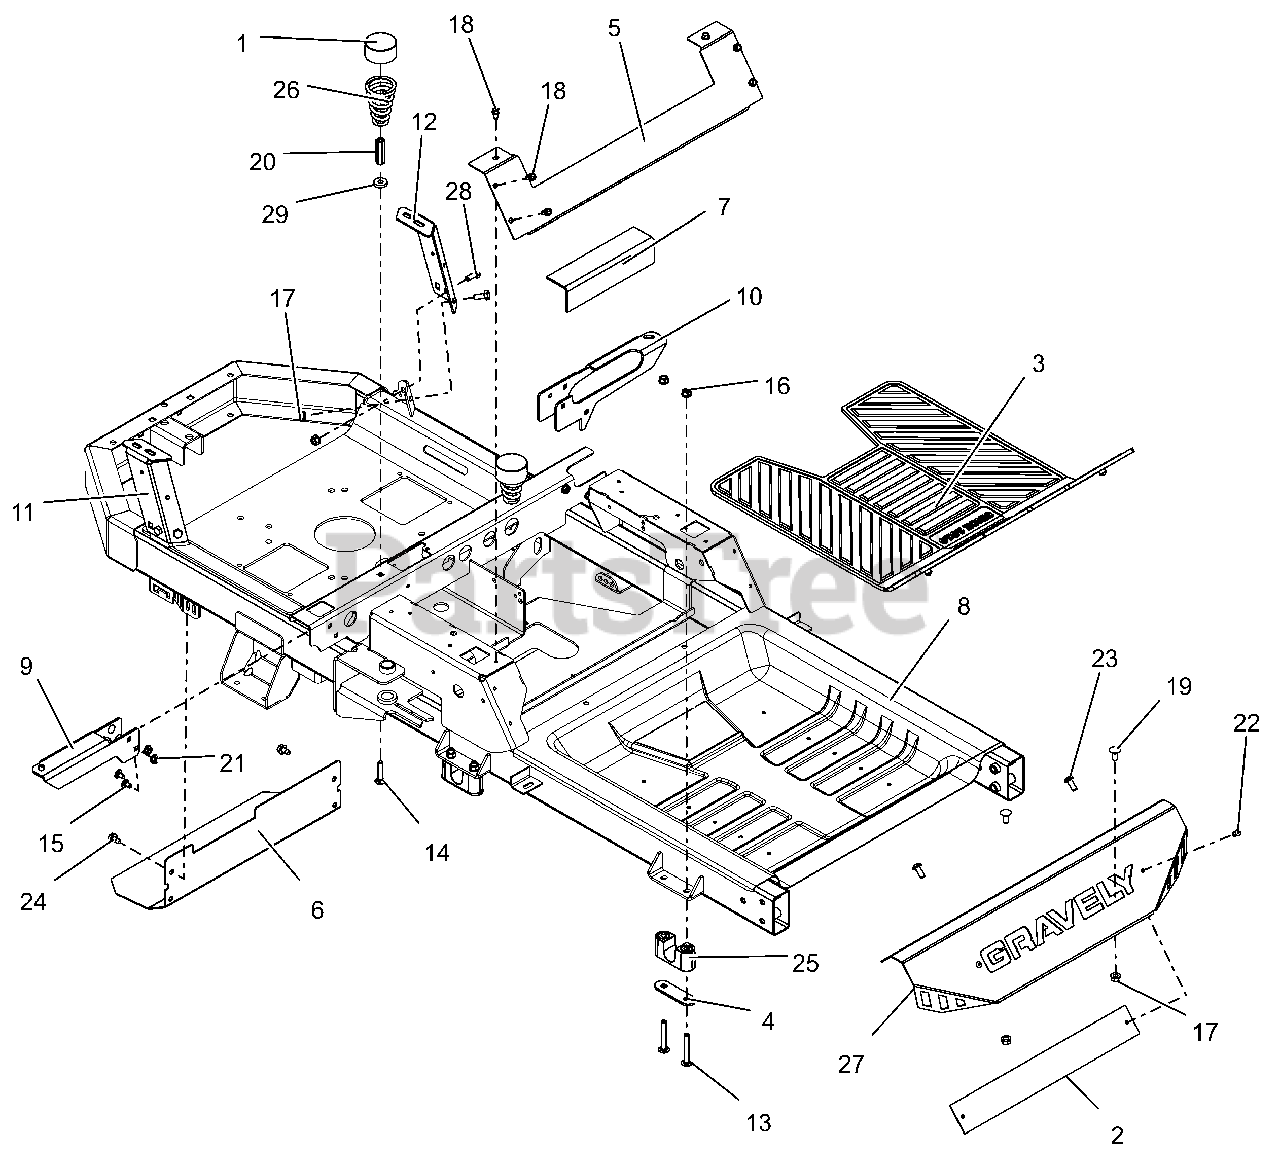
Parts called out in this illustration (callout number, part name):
2	PLATE, BACK FOOT-REST XL
3	FLOOR MAT, RUBBER - GRAVELY
4	PLATE, BEARING SUPPORT
5	PLATE, SEAT KICK
6	HEAT, SHIELD
7	PAD, RUBBER-TANK
8	KIT, ZT-X/XL FRAME SERVICE
9	BRKT,CROSS EXTENSION - LH
10	BRKT,CROSS EXTENSTION - RH
11	MOUNT,FENDER-RH EXTENSION
12	MOUNT,FENDER-LH EXTENSION
13	BLT, RHSSN.31-18X2.25 G5 ZCC
14	BLT,RHSN .31-18X1.50 G5 ZCC
15	BLT, RHSSN.25-20X.500 G5 ZCC
16	NUT,LK-CTR-FLG .31-18 GF ZCC
17	NUT-LK-TOP-FLG .312-18 GF ZCC
18	SCR-TAP .25-20X.50 HWH ZCC
19	BLT,RHSN .31-18X.75 G5 ZCC
20	NUT, COUPLING .31-18X1.75 ZCC
21	NUT-LK-CTR-FLG .25-20 ZC120
22	RIVET, #66 STEEL POP PD BLACK
23	SCR-RDHDSKTAP .31-18X.75
24	SCR,TAP .312-18X.50 HWH TR ZCC
25	BSHG, DECK LIFT PIVOT
26	SPRING, SEAT
27	PLATE, FOOT - GRAVELY
28	BLT,HEX .31-18X.75 G5 ZCC
29	WSHR, FLT .328X.870X.179 ZCC
